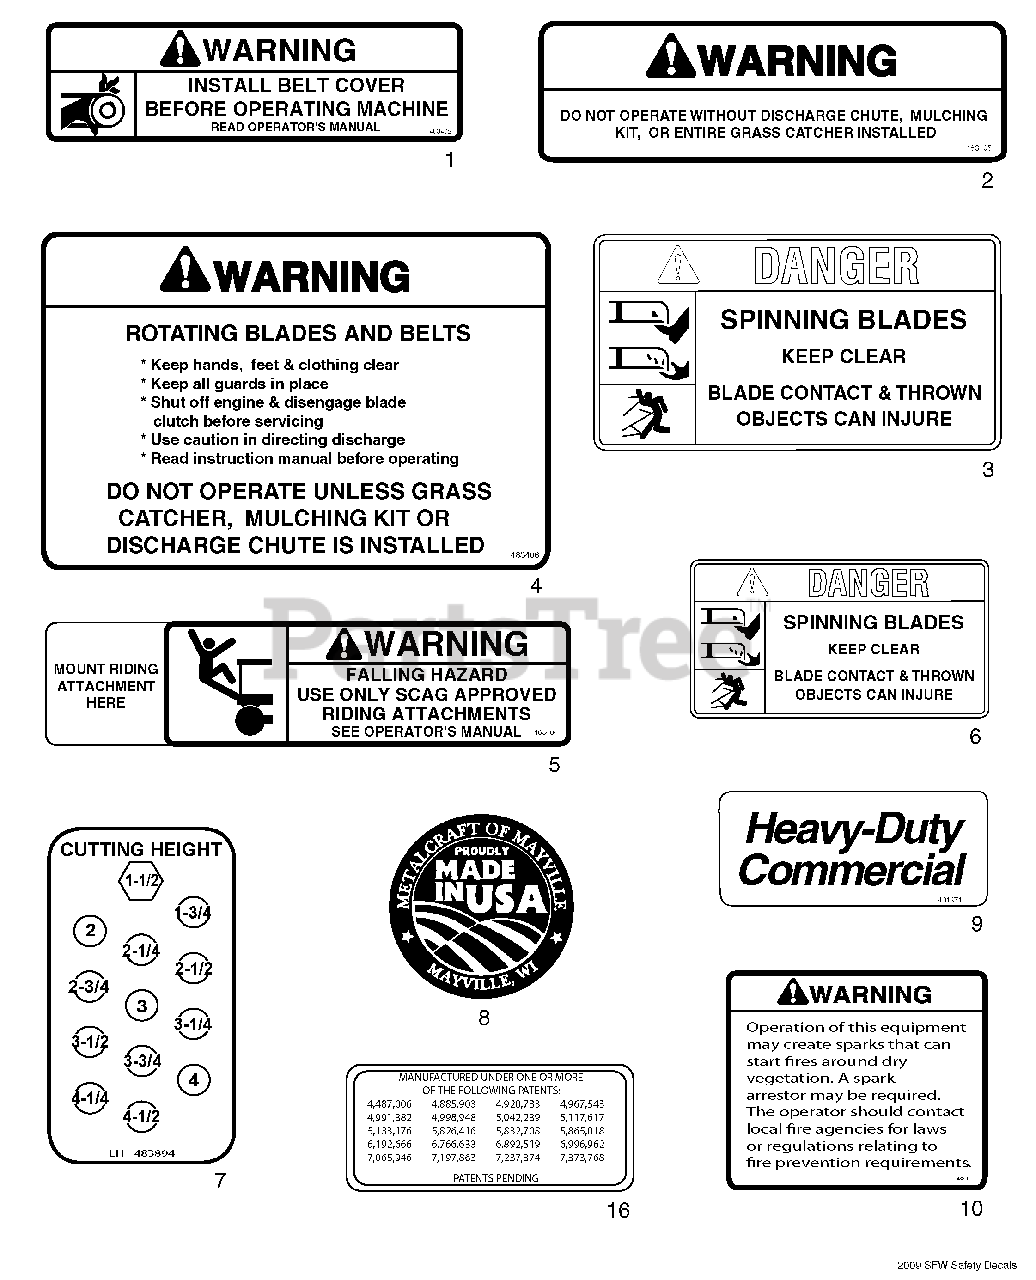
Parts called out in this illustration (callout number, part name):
1	Decal, Belt Cover
2	Decal, Discharge Chute
3	Decal, Spinning Blades
4	Decal, Warning-Rotating Blades
5	Decal, Sulky Attachment
6	Decal, Danger-Spinning Blades
7	Decal, Cutting Height LH
8	Decal, Metalcraft - Made in USA
9	Decal, Heavy Duty Commercial
10	Decal, Warning Spark Arrestor
16	Decal, Patents
